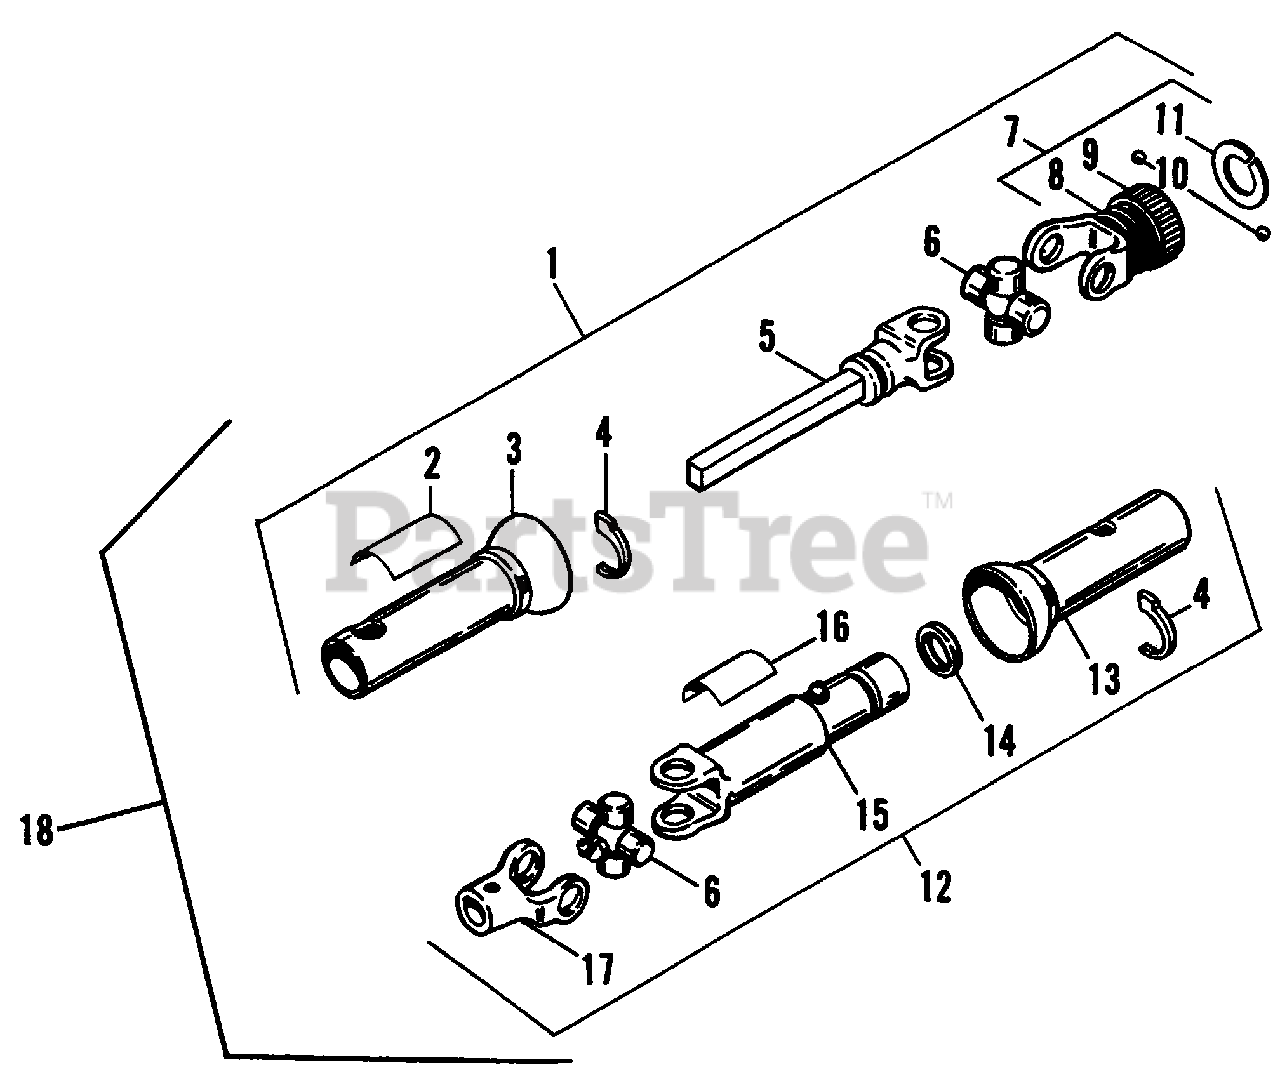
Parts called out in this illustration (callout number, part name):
1	DRIVE SHAFT ASSY.-TRACTOR HALF
2	SHIELD DECAL, Outer Shield
3	SHIELD, Outer
5	YOKE & SHAFT ASSY.
6	JOURNAL ASSY.
7	YOKE ASSY.
12	DRIVE SHAFT ASSY.-IMPLEMENT HALF
13	SHIELD, Inner
14	NYLON BEARING
15	YOKE & TUBE ASSY.
16	DANGER LABEL
18	ASSY., Complete
